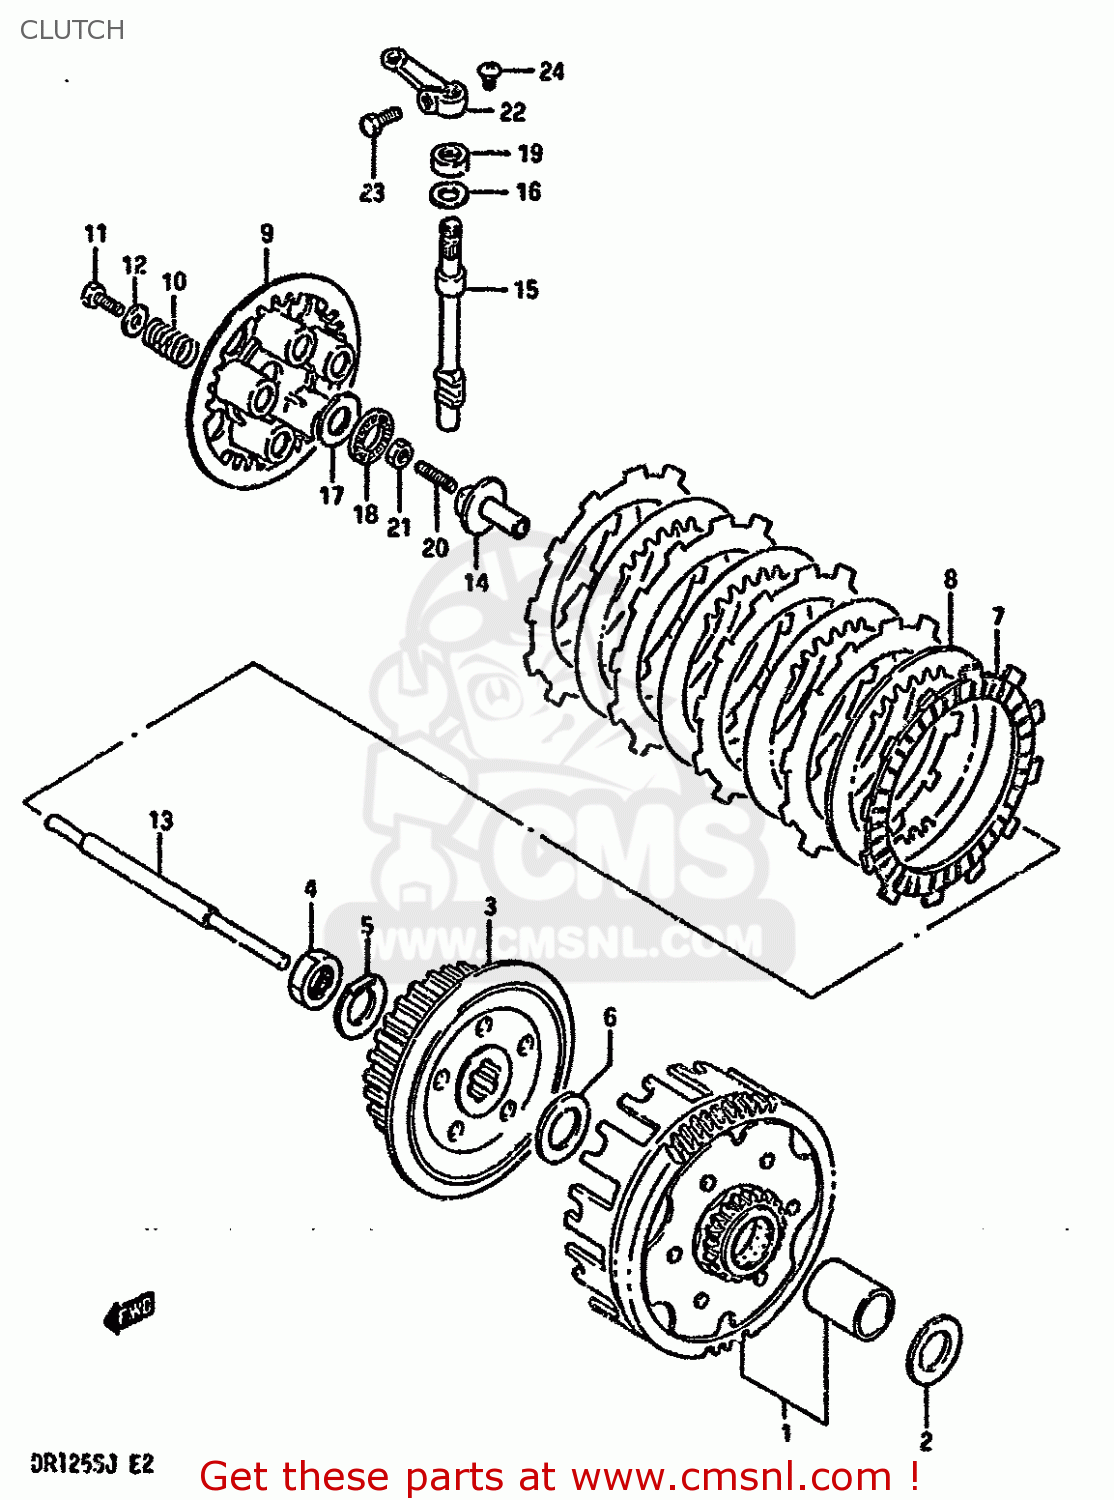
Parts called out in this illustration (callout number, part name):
1	GEAR ASSEMBLY,PRIMARY DRIVE
2	WASHER
3	HUB,CLUTCH SLEEVE
4	NUT
5	WASHER
6	WASHER
7	PLATE,CLUTCH DRIVE (MCA)
8	PLATE,CLUTCH DRIVEN (NAS)
9	PLATE,CLUTCH PRESSURE
10	SPRING
11	BOLT(5X16)
12	WASHER (5.5X16X1.2)
13	ROD,CLUTCH PUSH
14	PIECE,CLUTCH PUSH
15	CAMSHAFT,CLUTCH RELEASE
16	WASHER,THRUST
17	WASHER
18	BEARING(15X28X2)
19	OIL SEAL
20	SCREW(6X25)
21	NUT 6MM
22	ARM,CLUTCH RELEASE
23	BOLT
24	SCREW
